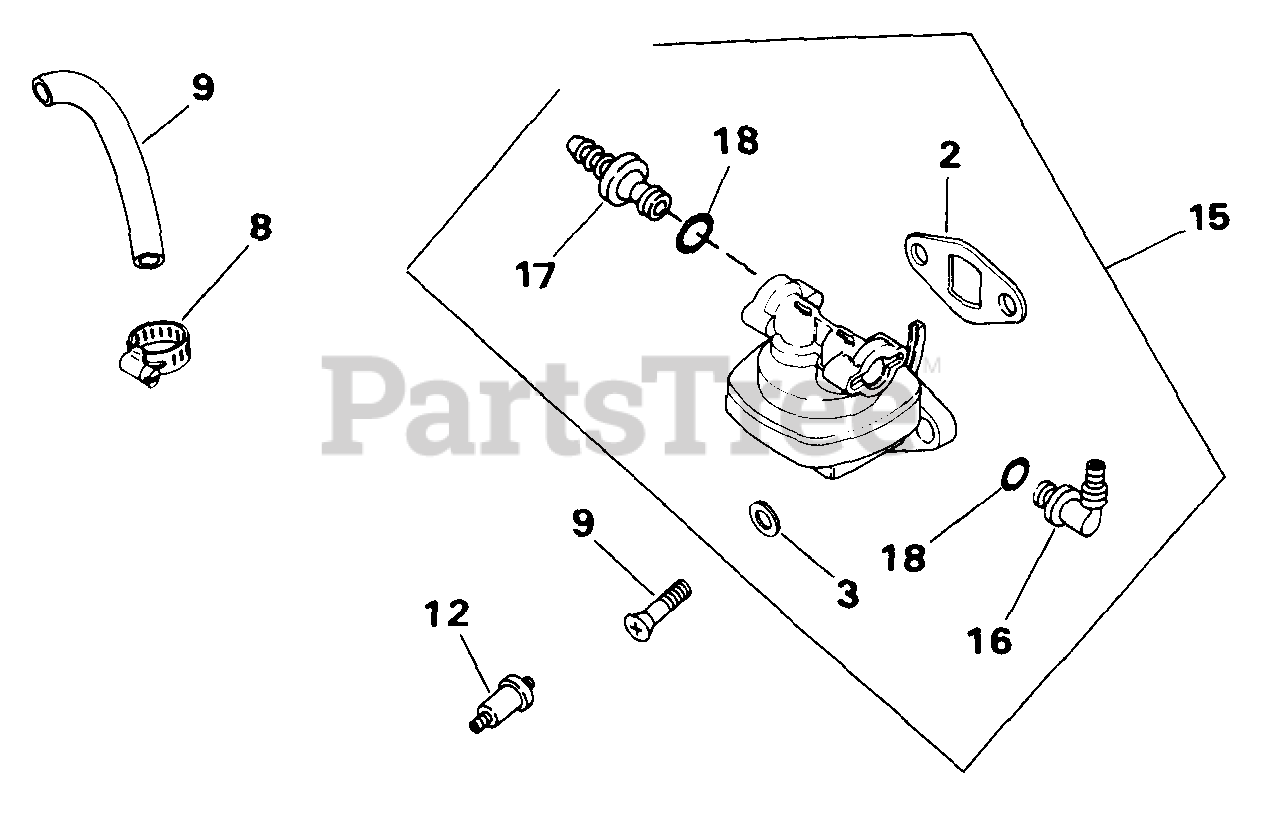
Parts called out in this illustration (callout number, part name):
2	GASKET - USE 25 041 09
3	WASHER, FLAT 1/4" (O.D. 1/2")
8	CLAMP, HOSE 1/2" USE 25 237 14-S
15	PUMP - USE 52 559 01
16	CONNECTOR, 90 DEG. W/O-RING-DISC.
17	CONNECTOR,STRAIGHT W/O-RING-DISC.
18	O RING FITTING - DISCONTINUED
